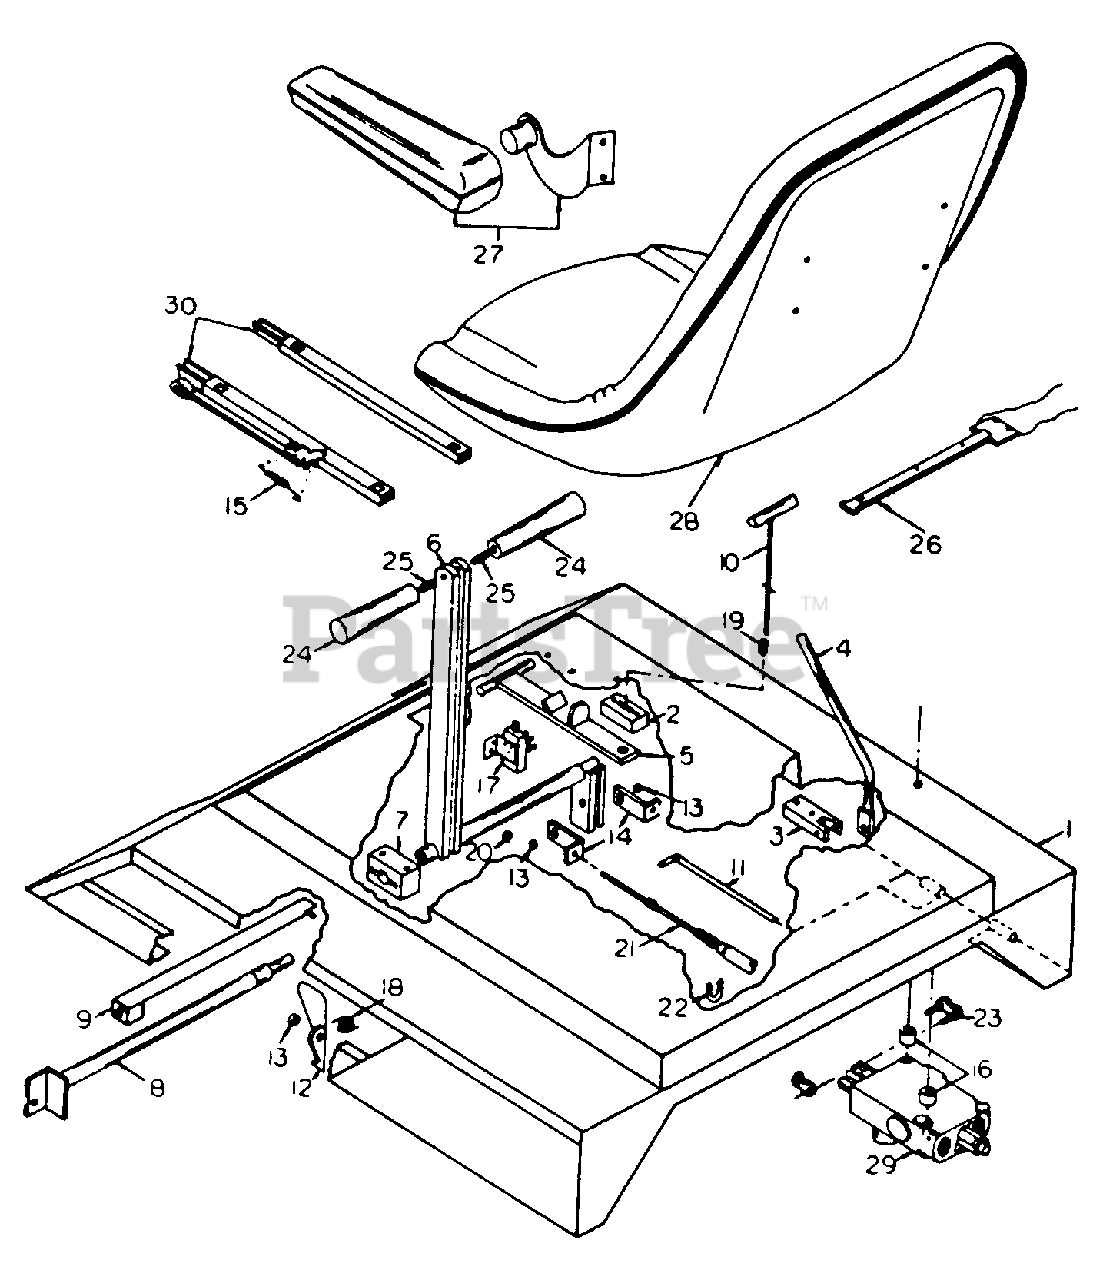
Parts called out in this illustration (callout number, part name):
1	Seat Lid
2	Lever Lock Block
3	Deck Lift Lever Mount
4	Deck Lift Lever
5	Lever Lock
6	Steering Levers
7	Steering Lever Block
8	Lid Prop
9	Lid Prop Lock
10	Lever Lock Handle
11	Seat Lid Pln
12	Sest Latch
13	Steerlng Cable Bushlng
14	Steering Cable End
15	Sprlng, Seat Rall
19	Spring
20	Grease Zerk
21	Steering Cable, 1/4"
22	Steering Cable Clamp, 1/4"
23	Connectlng Link, No. 50
25	Stud, 3/8"
27	Arm Rest
28	Seat
29	Hydraulic Deck Valve
30	Seat Rail Kit
